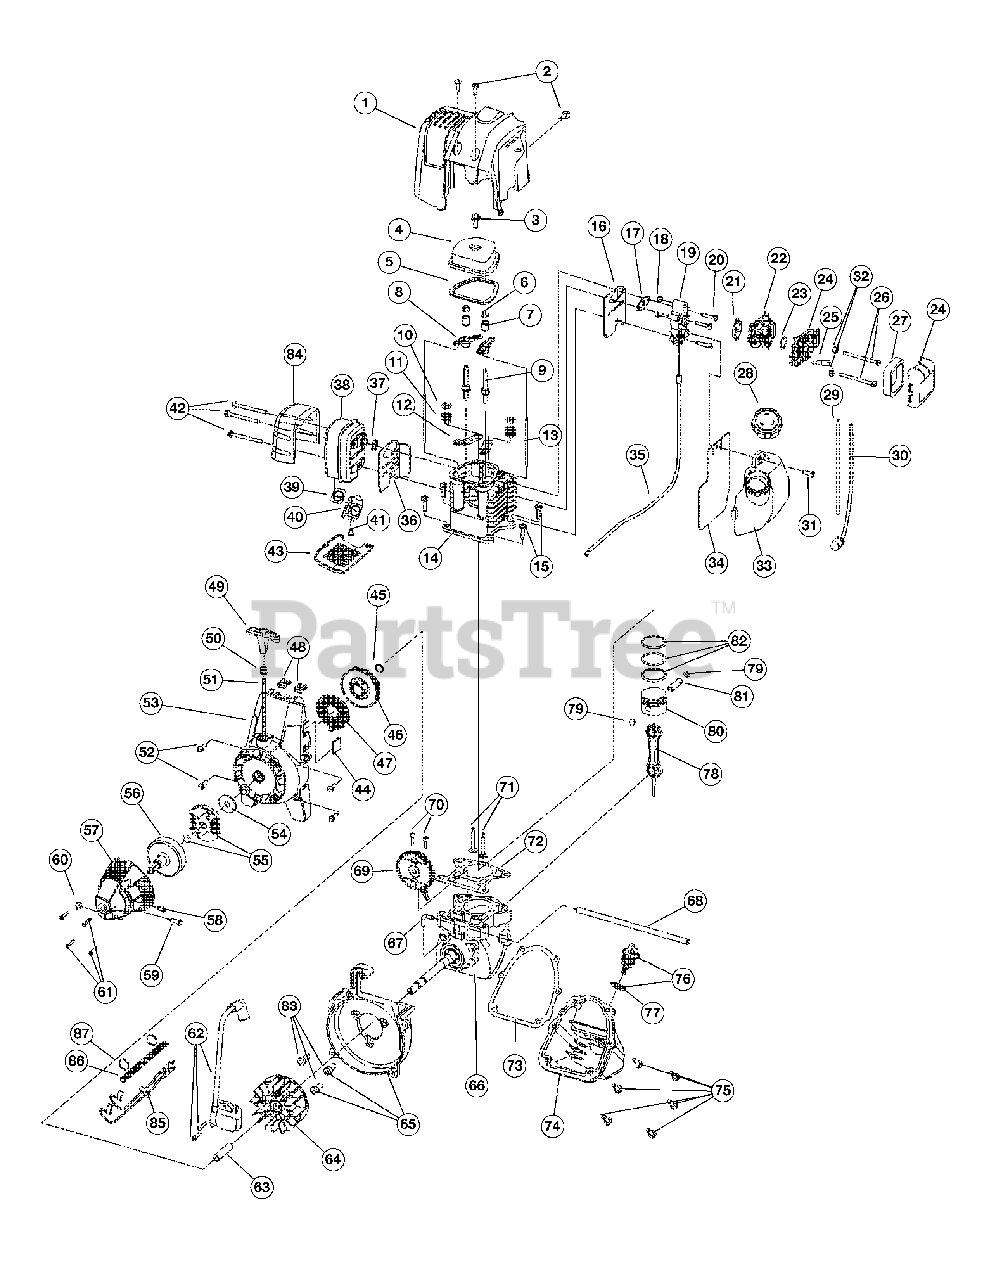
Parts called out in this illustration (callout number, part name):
1	Engine Cover
2	Engine Cover Screws
3	Valve Cover Screw
4	Valve Cover
5	Valve Cover Gasket
6	Rocker Adjustment Nut
7	Rocker Arm Pivot
8	Rocker Arm
9	Rocker Arm Stud
10	Valve Spring Retainer
11	Valve Spring
12	Push Rod Guide
13	Push Rod
14	Cylinder Assembly (includes 9, 12, 15, 71 & 72)
15	Cylinder Screw
16	Intake Baffle
17	Carburetor Mount Gasket
18	Nut
19	Carburetor Mount (includes 18)
20	Carburetor Mount Screw
21	Carburetor Gasket
22	Carburetor with Primer
23	O-Ring, Carburetor
24	Air Filter Assembly (includes 27)
25	Breather Tube
26	Air Filter Mounting Screw
27	Air Filter
28	Fuel Cap
29	Fuel Return Line
30	Fuel Pick-Up Line with Filter
33	Fuel Tank Assembly (includes 28-30)
34	Fuel Tank Shield
35	Throttle Cable
36	Muffler Baffle
37	Muffler Gasket
38	Muffler (includes 37, 39-41)
39	Spark Arrestor Screen
40	Screen Cover
42	Muffler Mounting Screw
43	Muffler Cover
44	Wire Grommet
45	Pulley Retainer
46	Recoil Pulley
47	Recoil Spring
48	Nut Clip
49	Pull Handle
50	Rope Guide
52	Starter Housing Screw
53	Starter Housing Assembly (includes 45-52)
54	Clutch Washer
55	Clutch with Spacer
56	Clutch Drum
57	Clutch Cover
58	Anti-Rotation Screw
59	Screw
61	Clutch Cover Screw
62	Ignition Module Assembly
64	Flywheel
65	Shroud Assembly (includes 83)
66	Crankcase Assembly (includes 67 & 68)
67	Breather Fitting
68	Breather Hose
69	Cam Bracket Assembly
70	Cam Bracket Screw
71	Valves, Intake and Exhaust
72	Cylinder Gasket
73	Oil Pan Gasket
74	Oil Pan (includes 73 & 75)
75	Oil Pan Screw
76	Dipstick Assembly (includes 77)
78	Connecting Rod
79	Wrist Pin Button
80	Piston (includes 82)
81	Wrist Pin
82	Piston Ring Set
83	Shroud Screw
84	Heat Shield
85	Wire Lead
86	Wire Lead Cover
87	Cable Clamp
